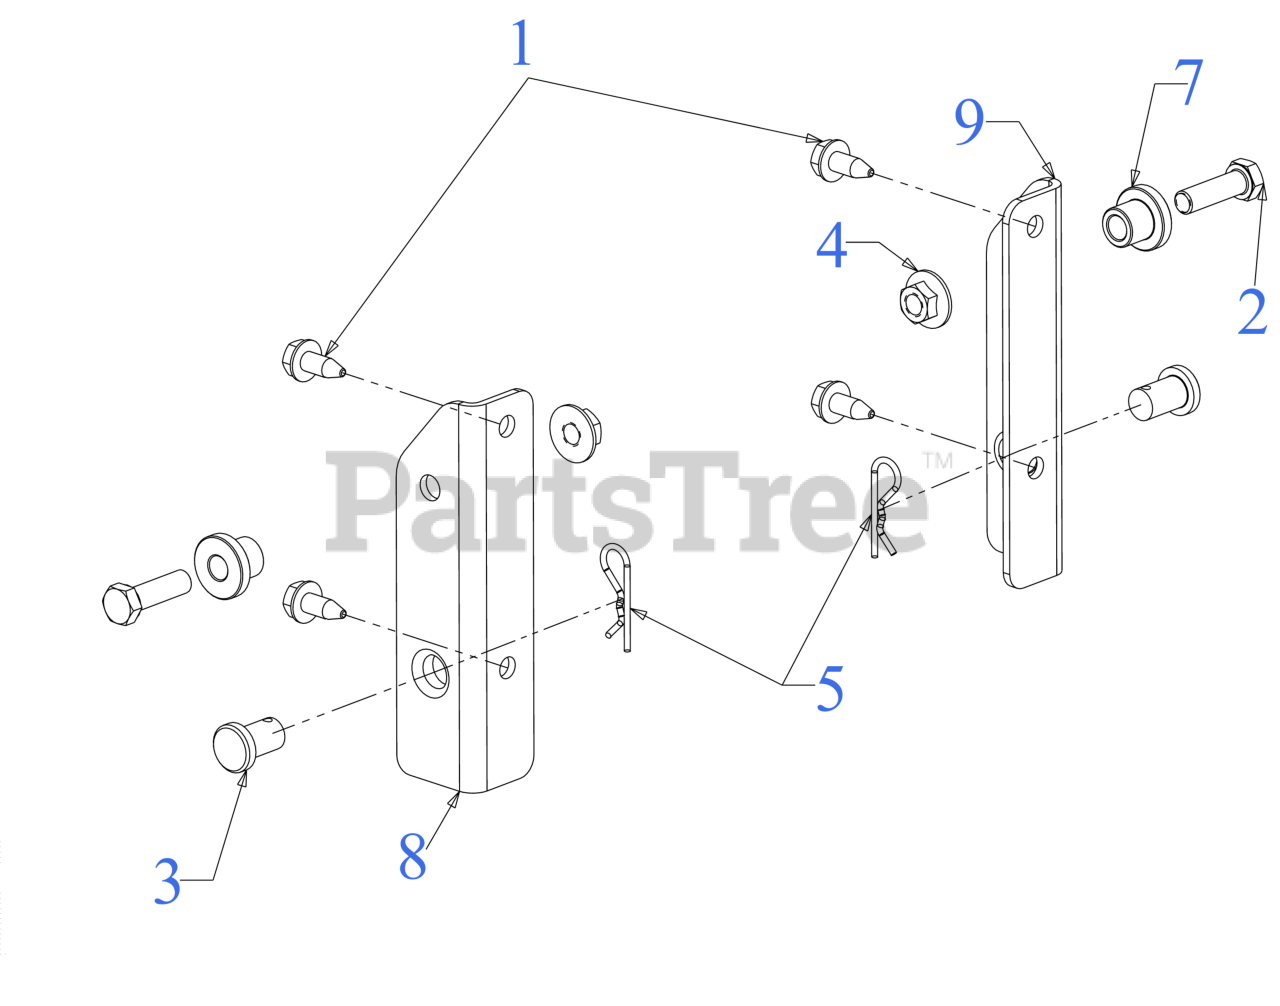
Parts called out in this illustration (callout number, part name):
1	SCREW 5/16-18 x .750
2	SCREW 3/8-16 x 1.25 GR5
3	LIFT BRACKET PIN
4	FLANGE LOCK NUT
5	INTERNAL COTTER PIN
7	SHOULDER SPACER
8	BRACKET (RH)
9	BRACKET (LH)
